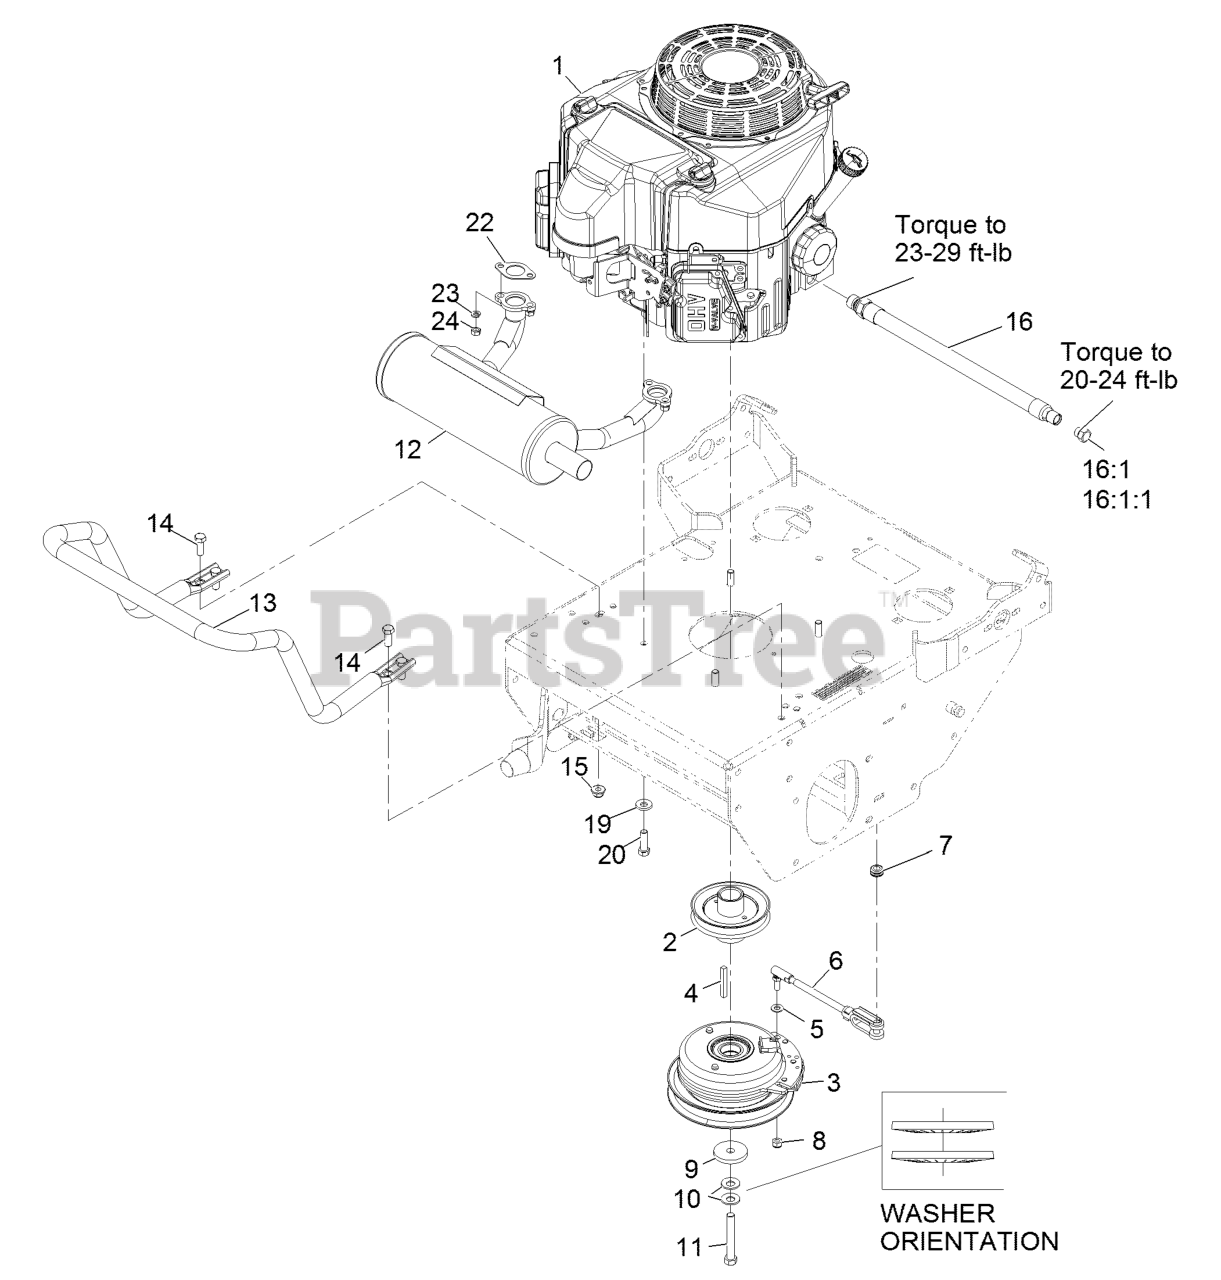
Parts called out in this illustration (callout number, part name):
2	SHEAVE, W/ HUB
3	CLUTCH, 105 FT/LBS, 1.13
4	KEY-SQUARE
5	WASHER-PLAIN
6	ASM, CLUTCH ANCHOR
7	GROMMET
8	NUT-LOCK
9	WASHER-CLUTCH
10	WASHER-SPRING
11	SCREW-HH
12	MUFFLER-HORIZONTAL
13	GUARD-MUFFLER
14	SCREW-HH
15	NUT-HF, NI
16	ASM, ENGINE OIL DRAIN HOS
16:1	PLUG-HH
16:1:1	O-RING
19	WASHER-BELLEVILLE
20	SCREW-HH
22	GASKET-EXHAUST
23	WASHER-LOCK
